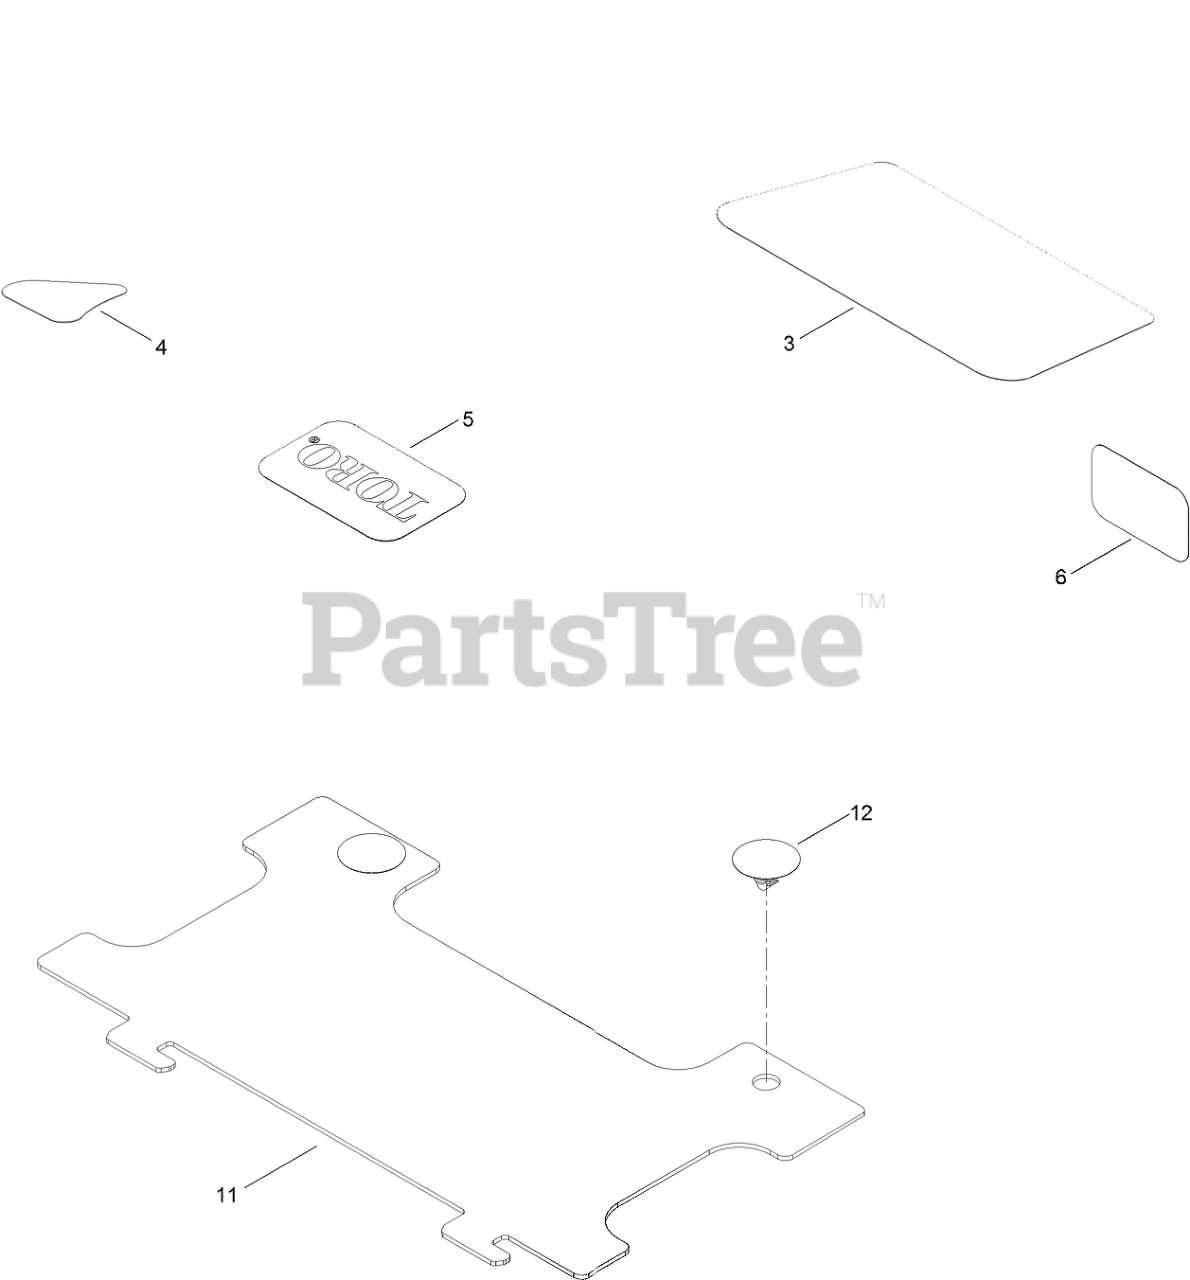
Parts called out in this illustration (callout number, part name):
3	DECAL-ENGINE
4	DECAL-DRAIN, OIL
6	PLACARD-INTAKE
11	SHIELD
12	RIVET-PLASTIC
